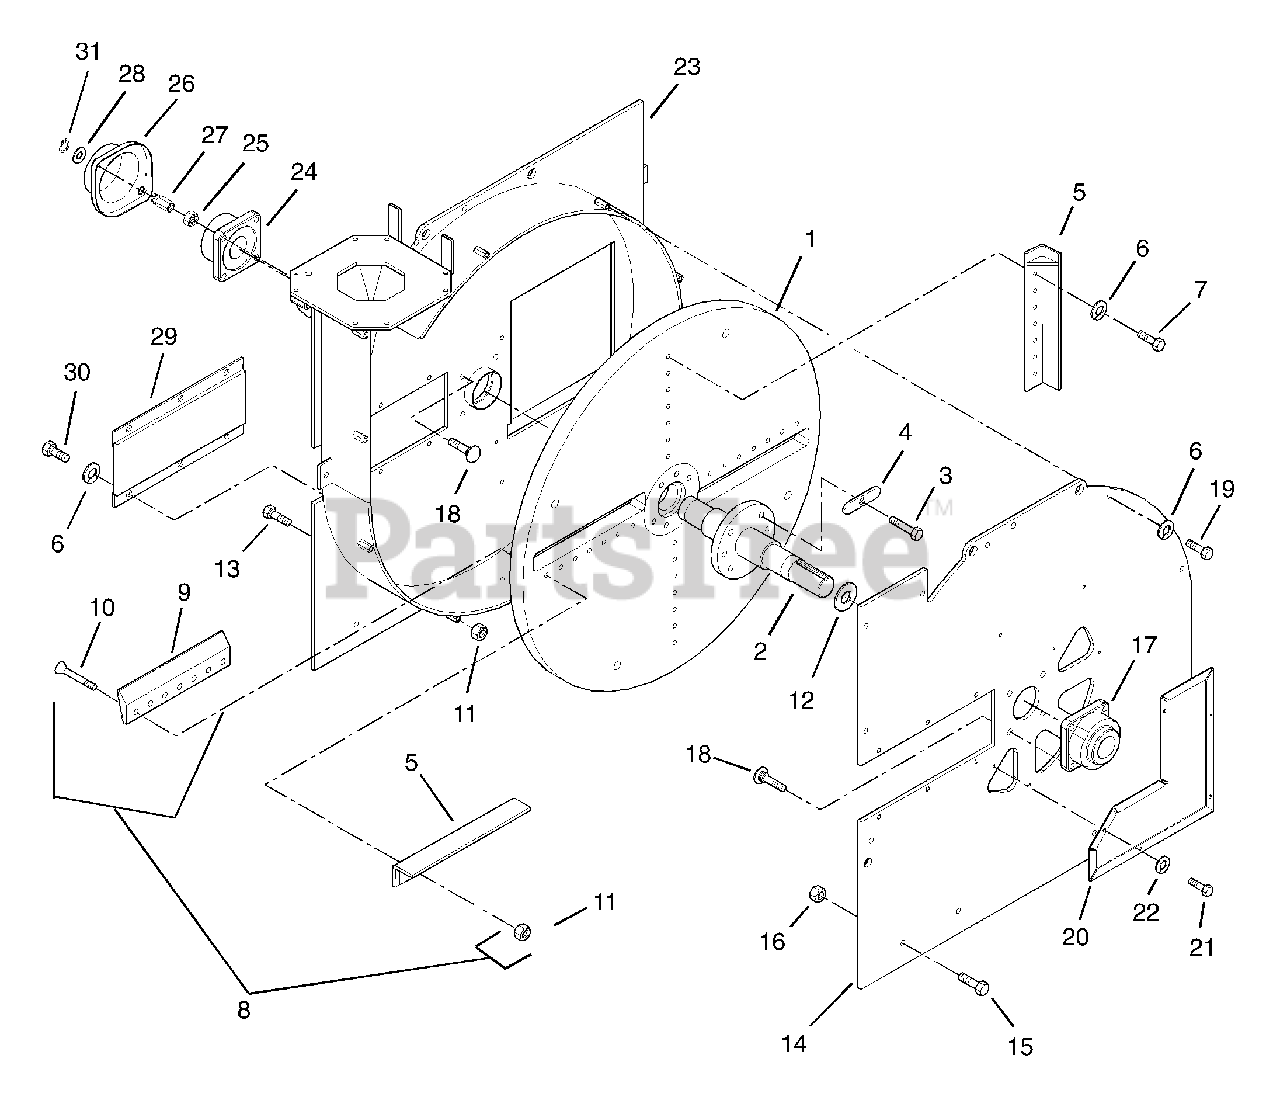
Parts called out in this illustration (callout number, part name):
1	Flywheel
2	Flywheel Shaft Weldment
3	Bolt-Hex .62-11 x 2.25 Grade 8
4	Lock Tab
5	Impeller Weldment
6	Washer-Lock .50 x .125
7	Bolt-Hex .50-13 x 1.25 Grade 5
8	Chipper Knife Set 495
10	Screw-Socket Head .50-13 x 3.5 Grade 8
11	Nut-Locking .50-13
12	Arbor Shim
13	Bolt-Hex .50-13 x 1.25
14	Housing (Front)
15	Bolt-Hex .75-10 x 1.50 Grade 5
16	Nut-Locking-Center .75-10
17	Bearing-Flange 2.00
18	Rib Neck Bolt
19	Bolt-Hex .50-13 x 1.75 Grade 8
20	Screen Frame Weldment
21	Bolt-Hex .31-18 x 1.75 Grade 5
22	Washer-Lock .313 x .078
23	Housing (Rear)
24	Bearing-Flange 2.00 Inside Diameter-Non-Expandable
25	Nut-Locking Flex
26	Bearing Cover
28	Washer-Flat-Steel .754 X 1.125 X .062
29	Access Cover Weldment
30	Bolt-Hex .50-13 x 1.00 Grade 5
31	Ring-Retaining-External .750 x .042
